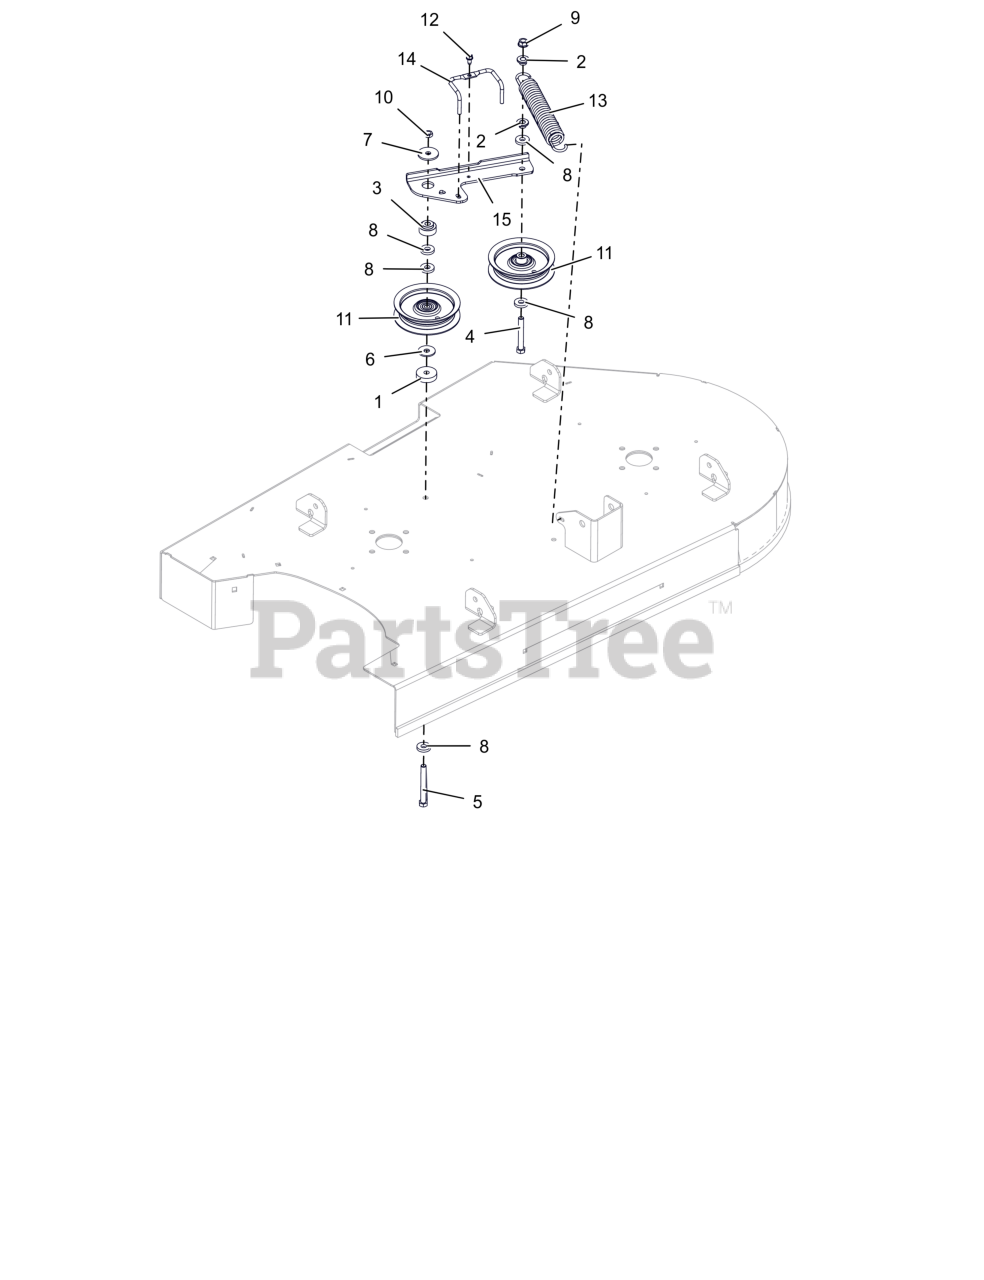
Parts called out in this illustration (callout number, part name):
1	SPACER, .39 X 1.50 X .380
2	BSHG-FLG .385X.500X.875X.406
3	BSHG, FLANGED
4	BLT, HEX .38-16X2.75 G5 ZCC
5	BLT, HEX .38-16X3.25 G5 ZCC
6	WSHR FL STL .406X1.25X.10ZC120
7	WSHR, FLT .380X1.50X.125 ZCC
8	WSHR, FLT .406X1.00X.188 ZCC
9	NUT-LK-CTR-FLG .375-16 GF ZCC
10	NUT-LK-CTR-JAM .375-16 GB ZCC
11	IDLER, FLAT - 4.06" X .75"
12	SCR-TAP .25-20X.50 HWH ZCC
13	SPRG, EXTENSION .170X1.385X6.7
14	WIREFORM, BELT FINGER
15	ARM, IDLER ZT (RED)
